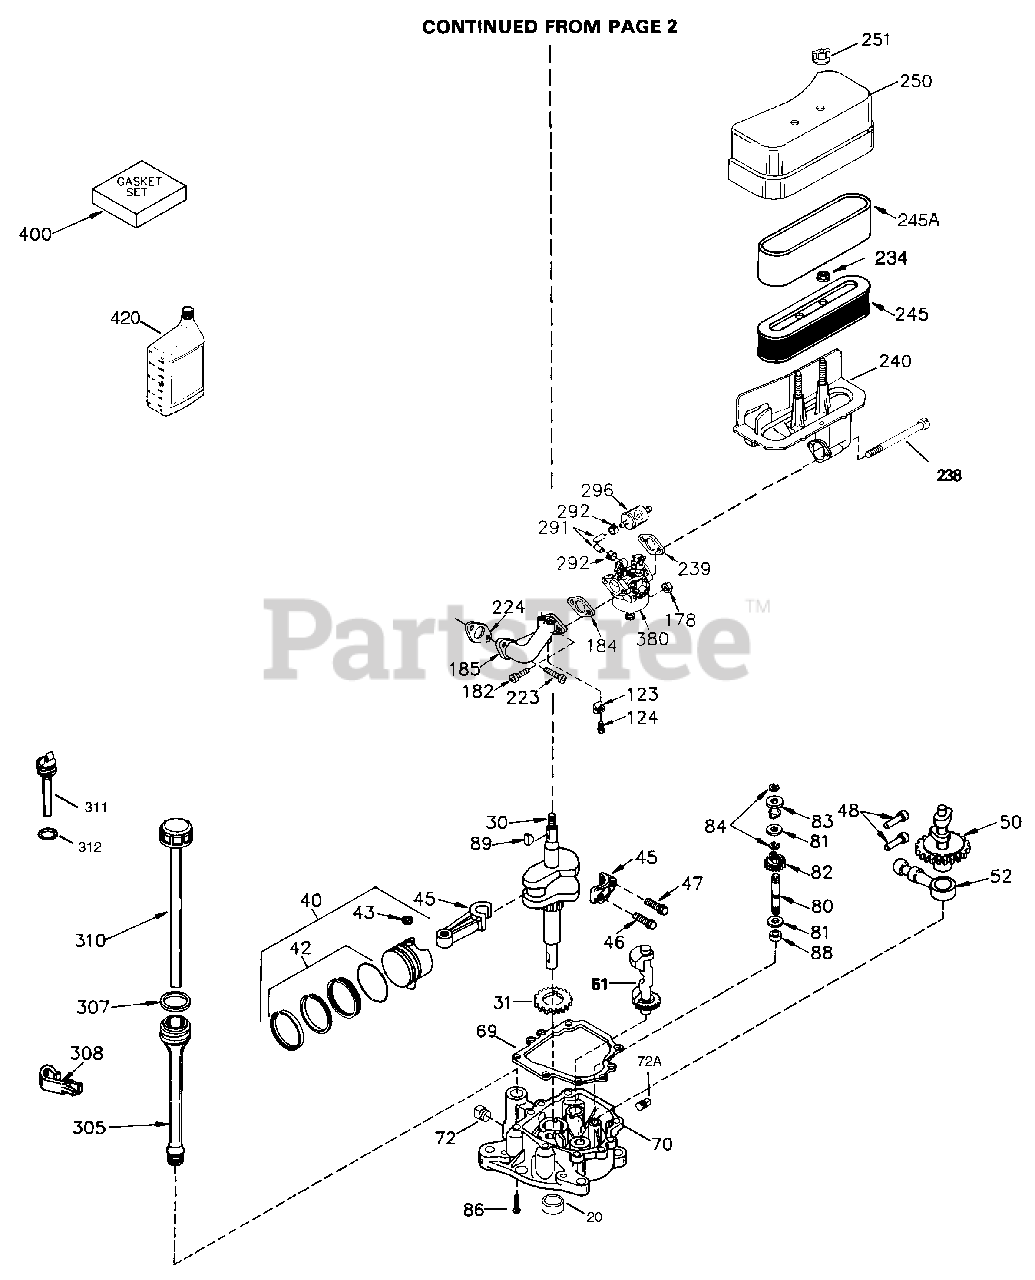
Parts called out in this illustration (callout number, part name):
20	Oil Seal
30	Crankshaft
31	Counterbalance Gear
40	Piston, Pin & Ring Set (Std) (Incl. 4 1, 42 & 43)
40	Piston, Pin & Ring Set (.010" OS) (In cl. 41, 42 & 43)
40	Piston, Pin & Ring Set (.020" OS) (In cl. 41, 42 & 43)
41	Piston & Pin Assembly (Std) (Incl. 43 )
41	Piston & Pin Ass'y. (.010" OS) (Incl. 43)
41	Piston & Pin Ass'y. (.020" OS) (Incl. 43)
42	Ring Set (Std.) (3-5/16")
42	Ring Set (.010" OS)
42	Ring Set (.020" OS)
43	Piston Pin Retaining Ring
45	Connecting Rod Ass'y. (Incl. 47)
47	Connecting Rod Bolt
48	Valve Lifter
50	Camshaft (MCR)
51	Counterbalance Weight
52	Oil Pump Ass'y.
69	* Mounting Flange Gasket
70	Mounting Flange (Incl. 72, 72A, 75 & 80)
72	Oil Drain Plug
80	Governor Shaft
82	Governor Gear Ass'y. (Incl. 81)
83	Governor Spool
84	Retaining Ring
86	Screw, 1/4-20 x 1-3/16"
88	Spacer (Incl. 81)
89	Flywheel Key
123	Intake Pipe Brace
124	Screw, 1/4-20 x 9/16"
178	Nut & Lock Washer 1/4-28
182	Screw, 1/4-28 x 1"
184	* Carburetor To Intake Pipe Gasket
185	Intake Pipe
223	Screw, Torx T-30, 5/16-18 x 1-1/8"
224	Intake Pipe Gasket
234	Nut & Lock Washer, 1/4-20
238	Screw, 10-32 x 1-17/32"
239	* Air Cleaner Gasket
240	Air Filter Body (Incl. 239)
243	Screw, 10-32 x 7/16"
245	Air Filter (Incl. 234) also available in Packaged Part #740015B
245A	Pre-Cleaner Air Filter also available in Packaged Part #740015B
250	Air Cleaner Cover
251	Wing Nut, 1/4-20
264A	Screw, 1/4-20 x 5/8"
277	Screw, 5/16-18 x 3-3/16"
292	Fuel Line Clamp
305	Oil Fill Tube
307	"O" Ring
308	Fill Tube Clip
310	Dipstick
370R	Warning Decal
380	Carburetor (Incl. 184)
400	* Gasket Set (Incl. items marked PK in notes) Incl. part #'s 26756 (1), 2727 2A (2),27896A (2),27915A (1),29673 (1 ),33263 (1),33629 (1),34041A (1) ,343 27A (1),34698A (1),34912 (1),34923A ( 1),35262A (1),35317 (1),35865 (1 )
900	Replacement engine None.
900	Replacement short block 752312A, orde r from 71-999
